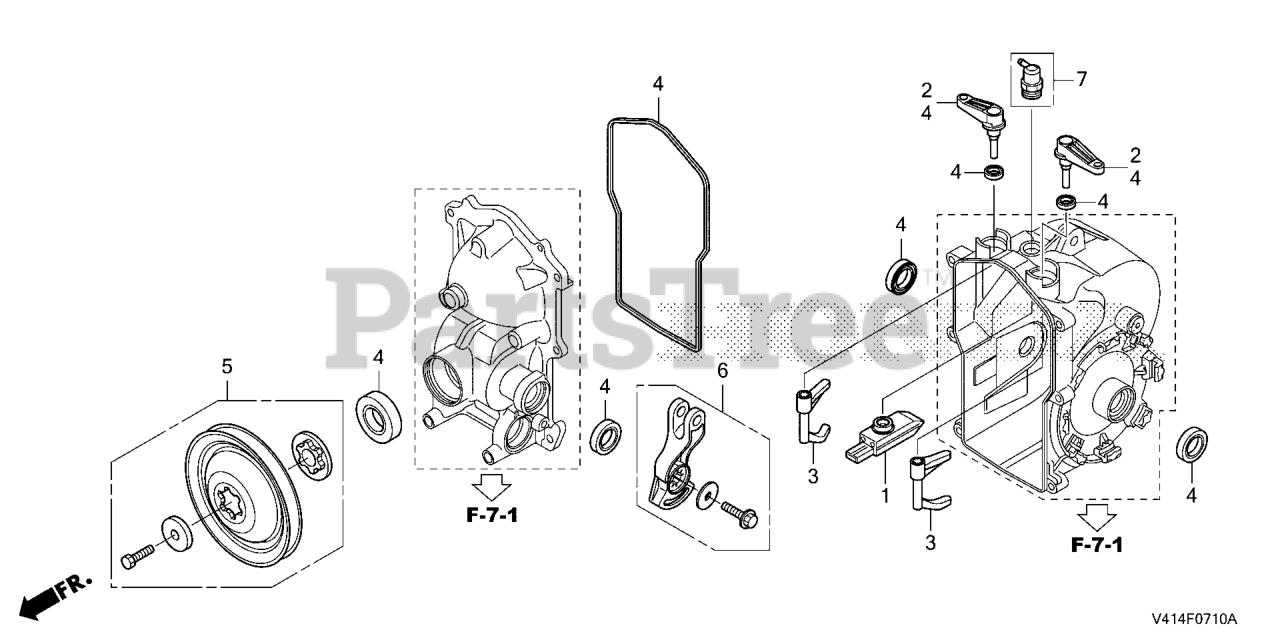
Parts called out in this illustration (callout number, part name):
1	DEFLECTOR OIL
2	SHAFT, SHIFT
2	SEAL SET, TRANSMISSION
3	FORK, SHIFT
4	SEAL SET, TRANSMISSION
5	PULLEY SET
